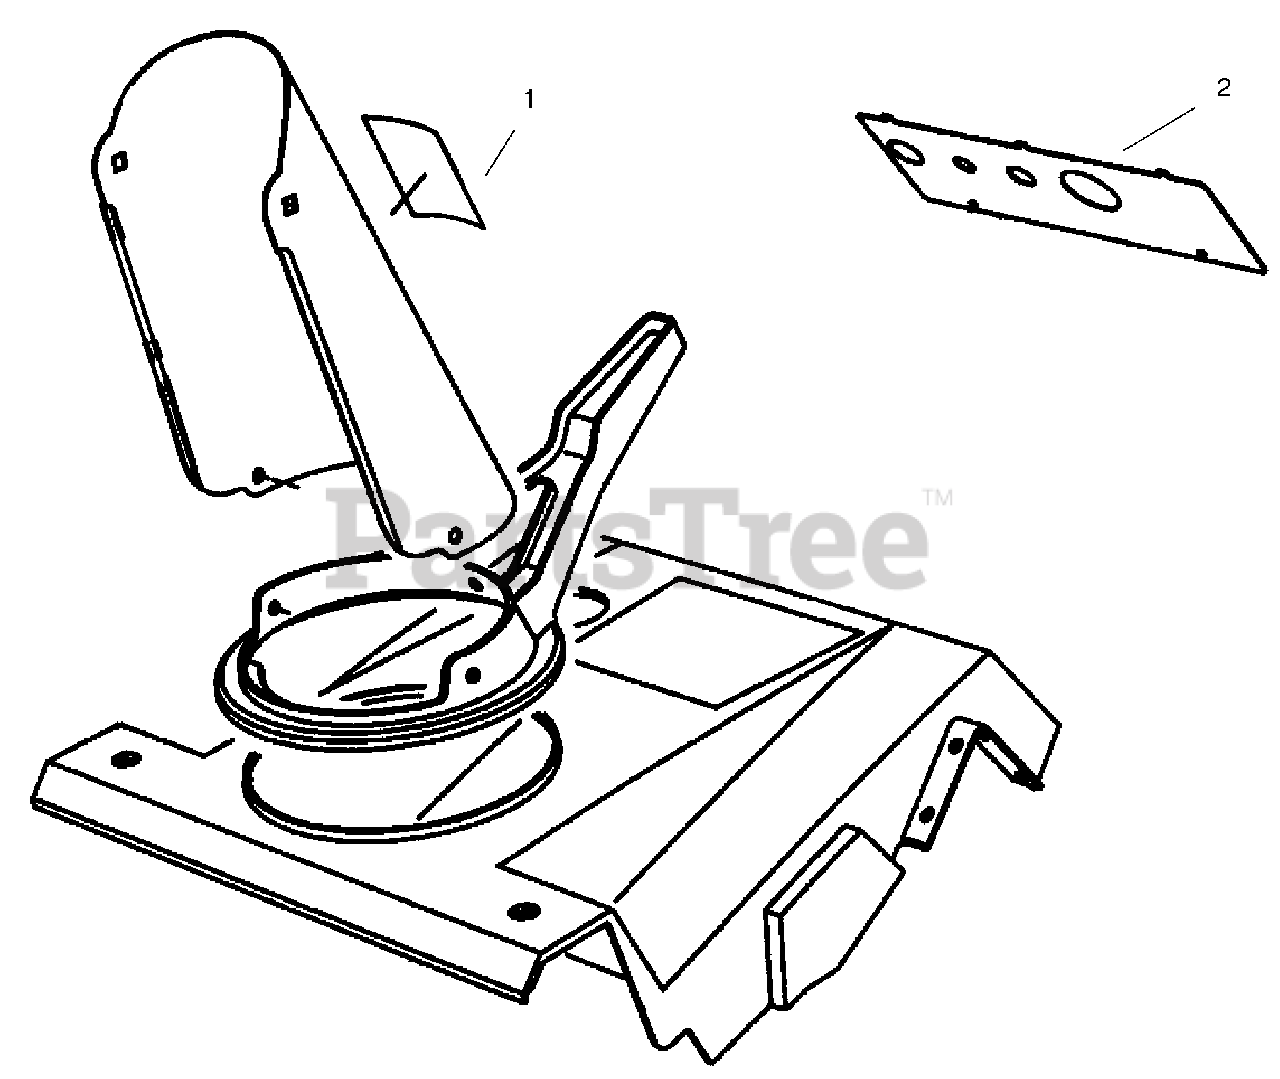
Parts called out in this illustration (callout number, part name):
1	Decal-Danger Discharge
2	Decal-Control Panel (Model No. 28220 Only)
2	Decal-Control Panel (Model No. 28222 Only)
